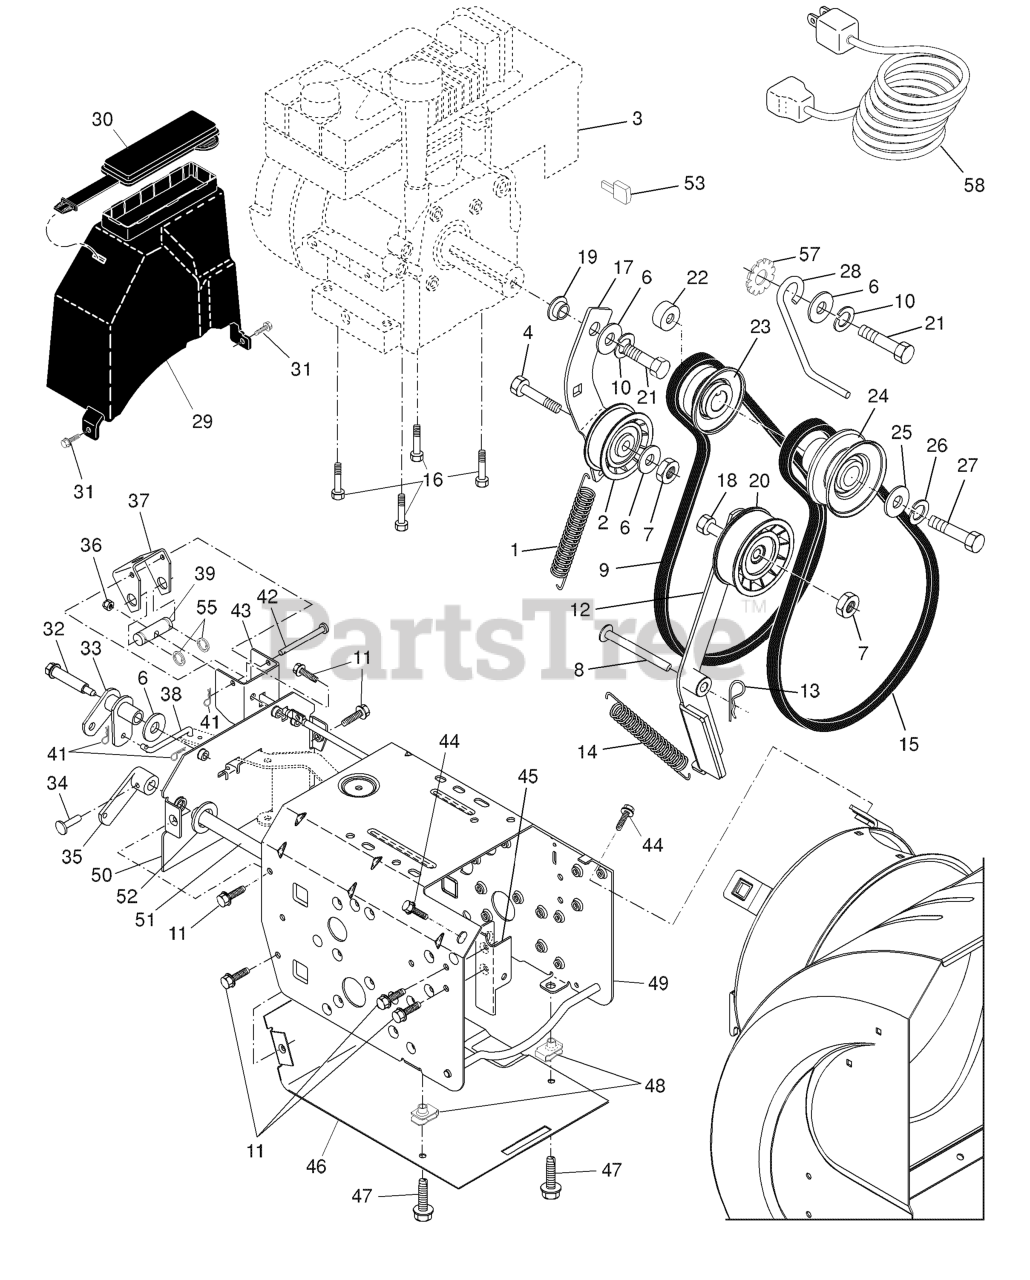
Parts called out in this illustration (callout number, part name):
1	RP SPRING, TRACTION IDLER
2	PULLEY.W/SPACER.2.25
4	BOLT.5/16-18X1-1/4 FULL.THREAD
6	STEEL WASHER
7	LOCKNUT 5/16-18
8	PIN, IDLER PIVOT
9	V-BELT, TRACTION DRIVE
10	WASHER.LOCK.HVY.HLCL.SPR.5/16
11	Screw, Hex Head 5/16-18 x 1/2
12	ARM PAD ASSY
13	RETAINER CLIP PM
14	SPRING, BRAKE
15	BELT.V.IMPELLER.DRIVE
16	BOLT 3/8-16X1-1/8
17	IDLER ARM
18	HEX BOLT
19	RP BUSHING, IDLER PIVOT
20	PULLEY.W/SPACER.2.75
22	SPACER.ENGINE.PULLEY
23	PULLEY,ENGINE TRACTION DRIVE
24	PULLEY, ENGINE IMPELLER DRIVE
25	WASHER, FLAT 3/8
26	LOCKWASHER
27	SCREW, HEX HD 3/8-24 X 1-3/8
28	BELT.GUIDE.RH
29	COVER.ASM.BELT/STORAGE
30	COVER.STORAGE.SNOW
31	SCREW
32	BOLT, SHOULDER 5/16-18
33	BELLCRANK SHIFTER
34	CLEVIS PIN
35	ARM, AUGER CONTROL
36	NUT.71038.31-18.HEX.NYLOCK
37	BRACKET, PIVOT
38	LINK, SPEED CONTROL
39	TRUNNION, TRACTION
41	RETAINER CLIP
42	PIN, PIVOT BRACKET
44	SCREW 3/8-16X1
45	BRACKET, IDLER PIVOT
46	PAN.BOTTOM.PLASTIC
47	SCREW, HEX HEAD, TAPPING
48	NUT.CENTERLOCK.5/16-
49	FRAME.WELD.PNT.998TGP
50	PLATE, FRAME END
51	SHAFT, AUGER CONTROL
52	THRUST WASHER
53	KEY, SAFETY IGNITION
55	RETAINING RING LT
57	WASHER EXT TOOTH LOCK 5/16
58	CORD.ELECTRIC.10FT.120V.SNOW
